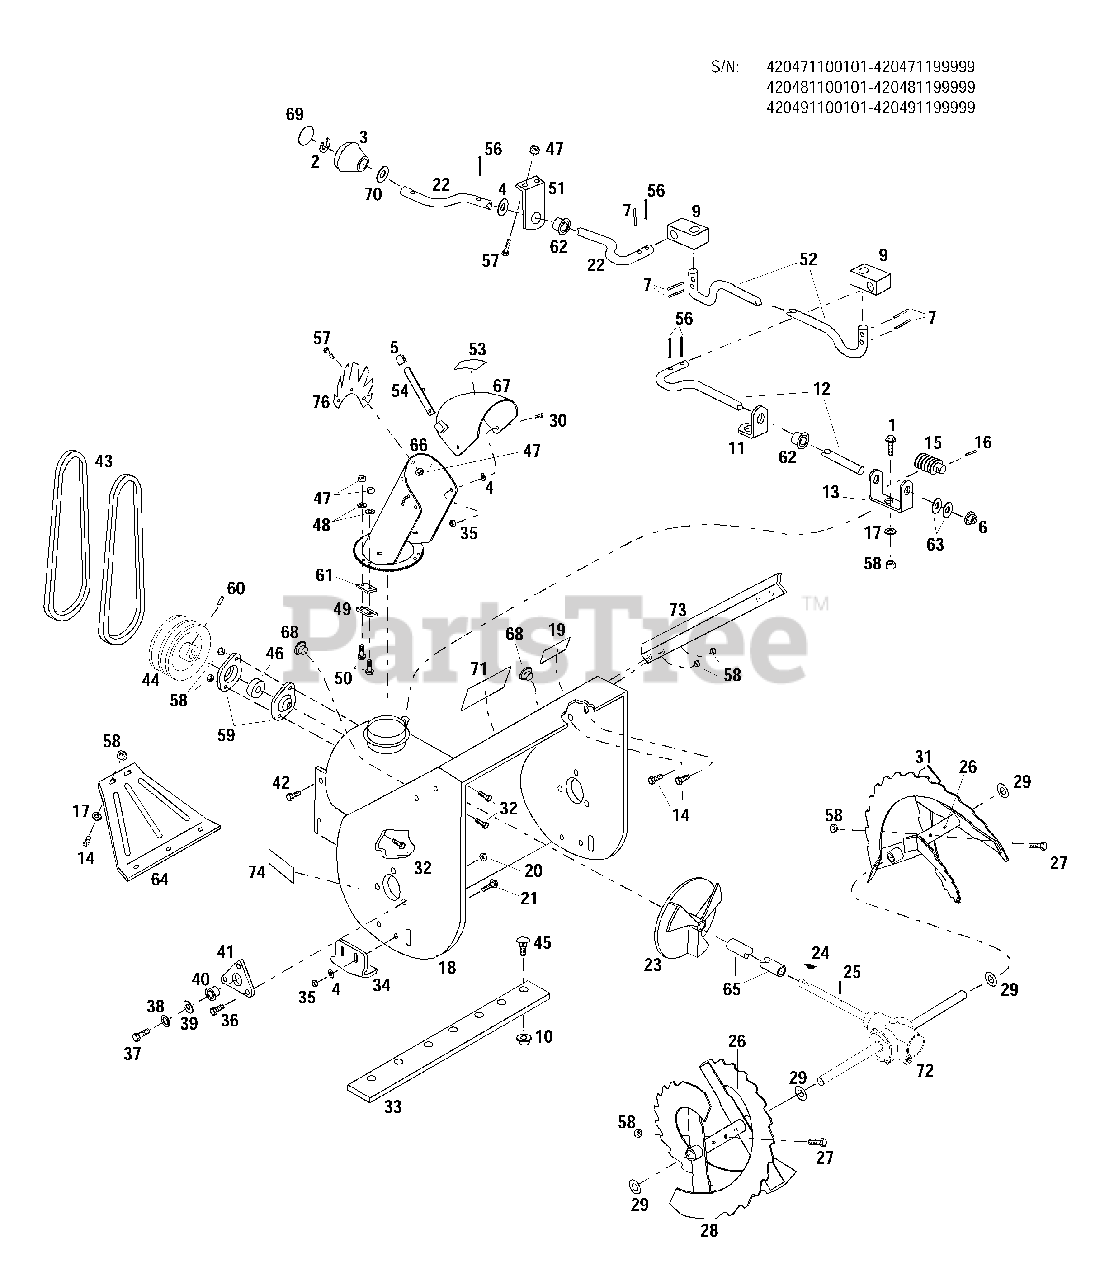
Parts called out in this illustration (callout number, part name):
1	Flange Bolt, 5/16-18 x 3/4
2	Retainer, 3/8
4	Flat Washer, 3/8
5	Grip
6	Flange Nut, 3/8-16
7	Roll Pin, 1/8 x 3/4
9	Swivel Block
10	Flange Nut, 5/16-18
11	Crank Support
12	Chute Control Shaft
13	Gear Support
14	Hex Head Cap Screw, 5/16-18 x 3/4
15	Worm Gear
16	Drive Pin, 3/32 x 3/4
17	Flat Washer, 5/16
18	Collector Housing Assembly
19	Warning Decal
20	Lock Nut, 1/4-20
21	Carriage Bolt, 3/8-16 x 3/4
22	Chute Control Crank
23	Impeller Fan
24	Hy Pro Key, 3/16 x 3/4
25	Roll Pin, 1/4 x 1-1/4
26	Grease Fitting
27	Shear Bolt Kit
28	26" Auger, R.H.
29	Special Washer, 1-1/64
30	Hex Head Cap Screw, 3/8-16 x 3/4
31	26" Auger, L.H.
32	Carriage Bolt, 5/16-18 x 3/4
33	Scraper Blade
34	Skid Shoe
35	Lock Nut, 3/8-16
36	Hex Head Cap Screw, 1/4-20 x 5/8
37	Hex Head Cap Screw, 1/2-13 x 3/4
38	Lock Washer, 1/2
39	Flat Washer, 1/2
40	Flange Bearing
41	Bearing Support
42	Flange Bolt, 3/8-16 x 1/2
43	V-Belt
44	Auger Sheave
45	Carriage Bolt, 5/16-18 x 5/8
46	Ball Bearing
47	Lock Nut, #10-24
48	Flat Washer, #10
49	Hold-Down Clip
50	Sems Screw, #10-24 x 7/8
51	Chute Control Support
52	Chute Crank Rod
53	Warning Decal
54	Adjusting Lever
56	Cotter Pin, 3/32 x 1/2
57	Truss-Head Bolt, #10-24 x 3/8
58	Lock Nut, 5/16-18
59	Flange Bearing
60	Set Screw, 5/16-18 x 3/4
62	Nylon Bushing
63	Nylon Washer
64	Housing Support
66	Discharge Chute Assembly
67	Discharge Cap
68	Button Plug
69	Spun Silver Inlay
70	Flat Washer, 3/8
71	Housing Logo Decal
72	Gear Case Assembly
73	Drift Slicer (complete kit)
74	Housing Side Decal
76	Chute Deflector
105	Multi-Purpose Grease, 8 oz
106	Loctite #242, .02 oz
